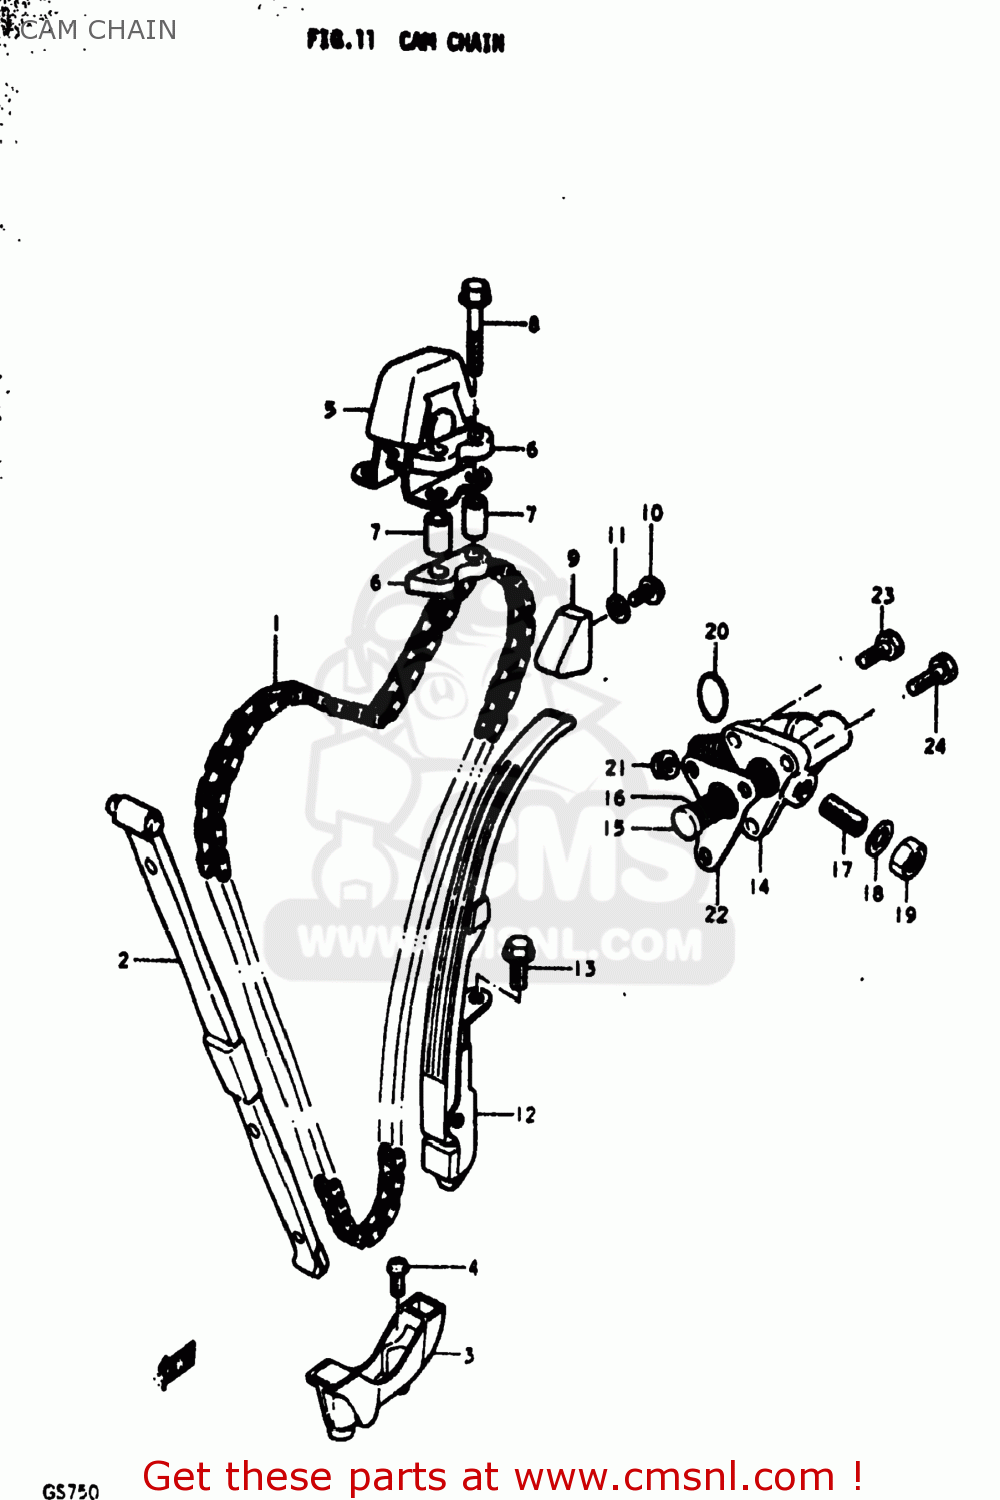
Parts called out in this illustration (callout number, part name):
1	CHAIN,CAMSHAFT DRIVE(120L)
2	GUIDE,CAM CHAIN
3	HOLDER,CAM CHAIN GUIDE
4	SCREW
5	IDLER,CAM CHAIN
6	CUSHION,IDLER
7	SPACER
8	BOLT
9	GUIDE,CAM CHAIN
10	BOLT
11	GASKET (NAS)
12	TENSIONER,CAM CHAIN
13	BOLT
14	ADJUSTER ASSEMBLY,TENSIONER
15	ROD,PUSH
16	SPRING
17	SCREW
18	WASHER
19	NUT
20	O-RING
21	NUT
22	GASKET,TENSIONER ADJUSTER (MCA)
23	SCREW
24	SCREW
